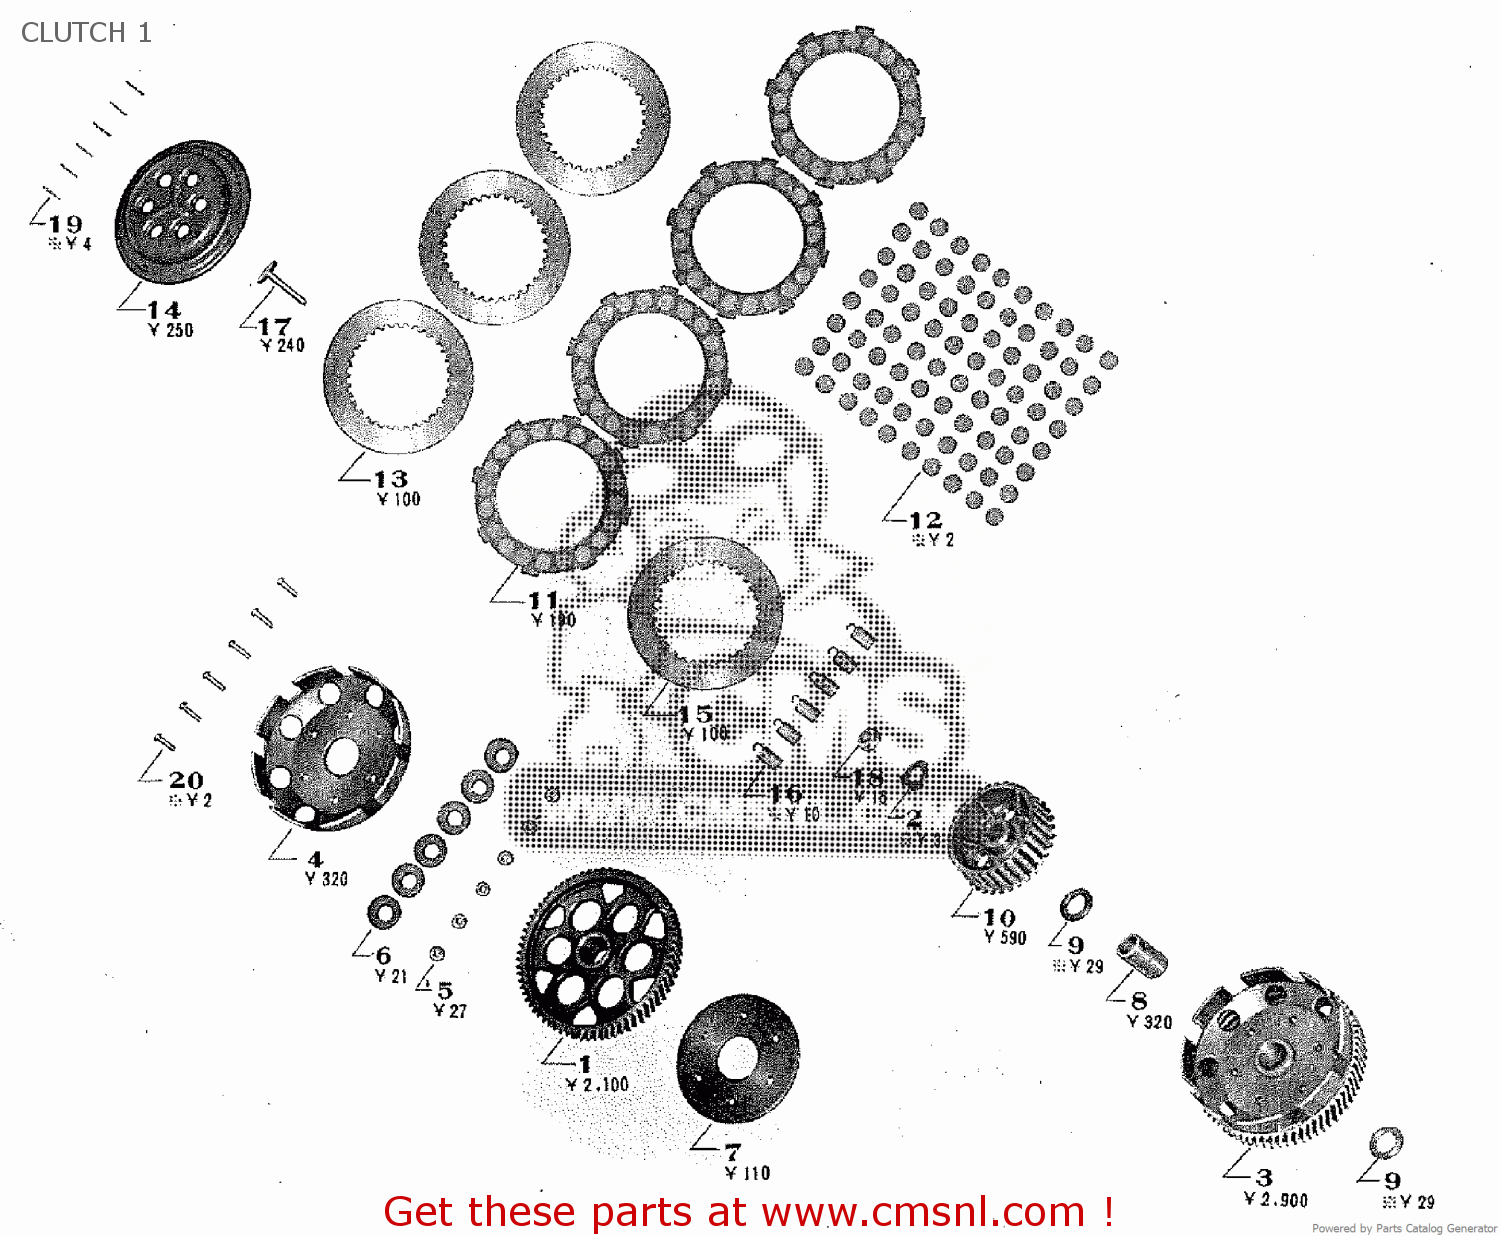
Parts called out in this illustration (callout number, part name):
1	PRIMARY GEAR
2	CLUTCH SLEEVE HUB SET WASHER
3	CLUTCH HOUSING ASSY.
4	CLUTCH HOUSING
5	CLUTCH DAMPER BUSH RING
6	CLUTCH DAMPER RUBBER
7	CLUTCH SET PLATE
8	CLUTCH HOUSING COLLAR
9	CLUTCH HOUSING THRUST WASHER
10	CLUTCH SLEEVE HUB
11	CLUTCH DRIVE PLATE COMP.
12	CLUTCH FRICTION CORK
13	CLUTCH DRIVEN PLATE
14	CLUTCH PRESSURE PLATE COMP.
15	CLUTCH INNER PLATE
16	CLUTCH SPRING
17	CLUTCH RELEASE ROD
18	CLUTCH SLEEVE HUB SET NUT
19	CLUTCH SPRING SET PIN
20	50X20 RIVET
